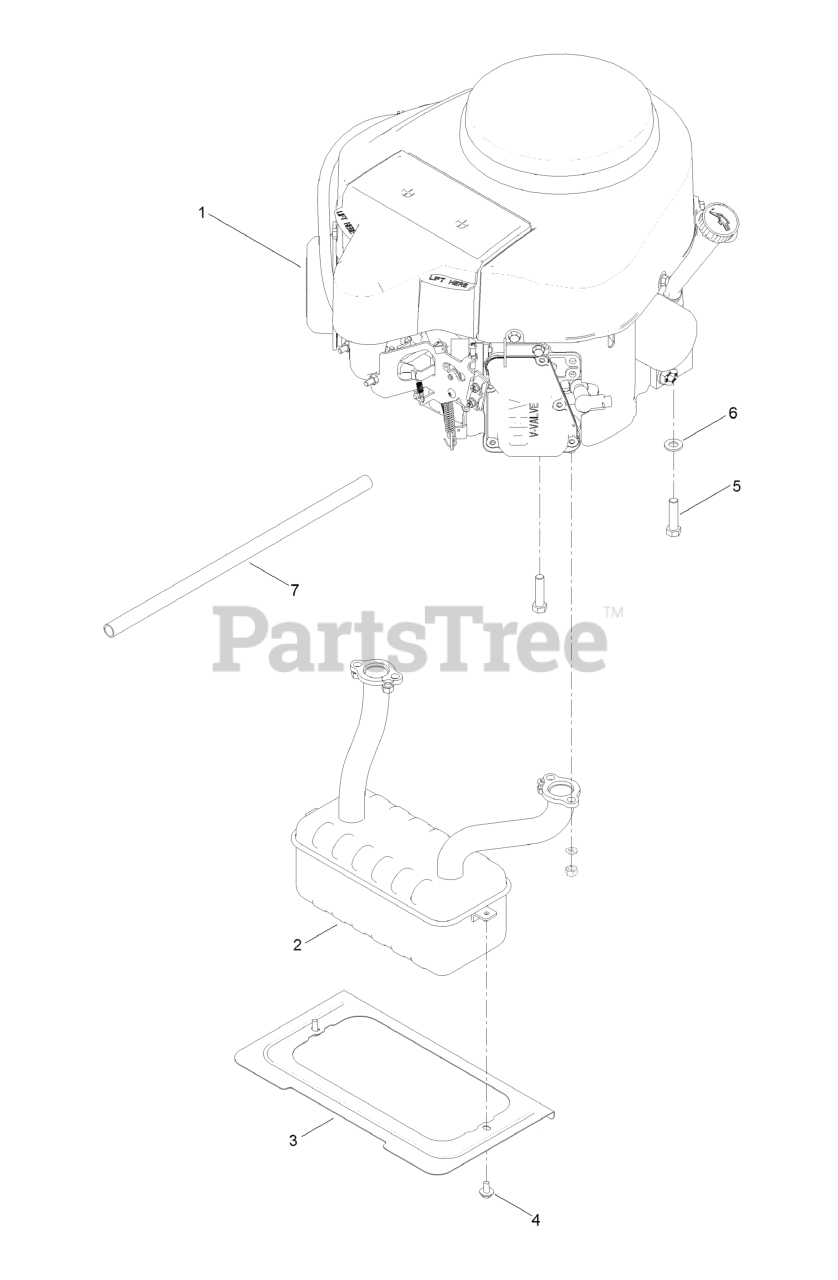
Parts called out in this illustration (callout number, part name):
2	Muffler
3	SHIELD-HEAT
4	SCREW-HHFTF
5	BOLT-HH
6	WASHER-FLAT
7	TUBE-DRAIN, OIL
